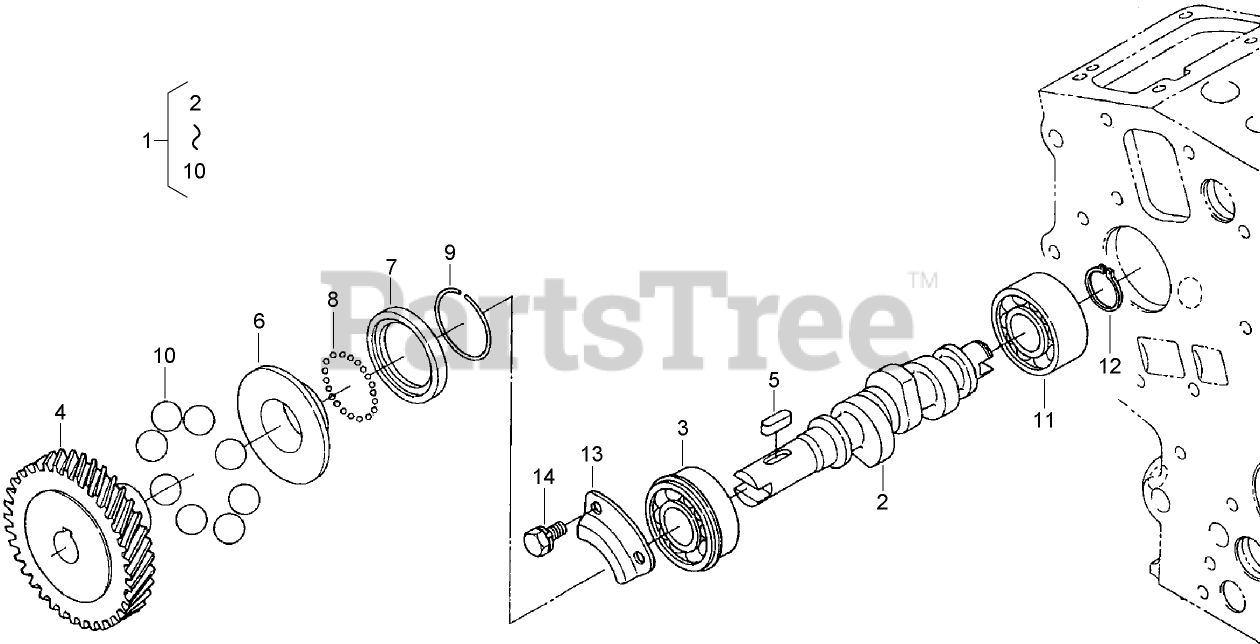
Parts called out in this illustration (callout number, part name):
1	CAMSHAFT ASM
2	CAMSHAFT-FUEL
3	BEARING-BALL
4	GEAR-PUMP, INJECTION
5	KEY-FEATHER
6	SLEEVE-GOVERNOR
7	CASE-BALL, GOVERNOR
9	CIRC-CLIP
11	BEARING-BALL
12	CIRC-CLIP, EXTERNAL
13	STOPPER-FUEL, CAMSHAFT
